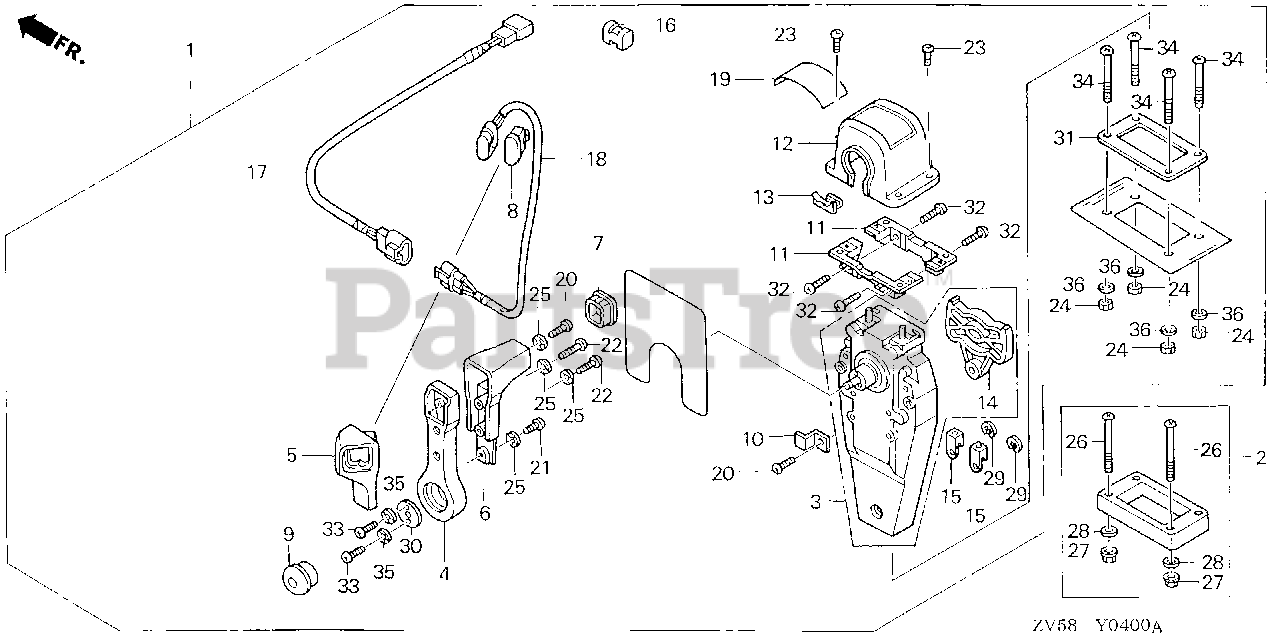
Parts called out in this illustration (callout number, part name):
1	BOX KIT, REMOTE CONTROL (TOP MOUNT SINGLE)(R)
2	SPACER KIT, REMOTE CONTROL BOX (TOP MOUNT SINGLE)
3	HOUSING ASSY., L. (INNER) (TOP MOUNT)
4	HANDLE, REMOTE CONTROL
5	COVER, L. GRIP
6	GRIP, REMOTE CONTROL HANDLE
7	CAP, GRIP
8	CAP, SWITCH
9	BUTTON, THROTTLE
10	PLATE, CABLE CLAMP
11	BRACKET, REMOTE CONTROL HOUSING
12	HOUSING, REMOTE CONTROL BOX
13	HOUSING, LEAD
14	PLATE, DWELL
15	TERMINAL, CABLE
16	SPACER, CABLE CLAMP
17	SUB-HARNESS ASSY., POWER TRIM-TILT (A)
18	SWITCH ASSY., POWER TRIM-TILT (A)
19	MARK, REMOTE CONTROL (SINGLE)
20	SCREW, PAN (5X16)
21	SCREW, PAN (5X10)
22	SCREW, PAN (5X20)
23	SCREW, PAN (4X10)
24	NUT, HEX. (5MM)
25	WASHER, LOCK (5MM)
26	SCREW, PAN (5X65)
27	NUT, FLANGE (5MM)
28	WASHER, PLAIN (5MM)
29	E-RING (6MM)
30	PLATE, HANDLE
31	GASKET, SINGLE
32	SCREW, PAN (5X18)
33	SCREW, PAN (6X18)
34	SCREW, PAN (5X40)
35	WASHER, LOCK (6MM)
36	WASHER, PLAIN (5MM)
